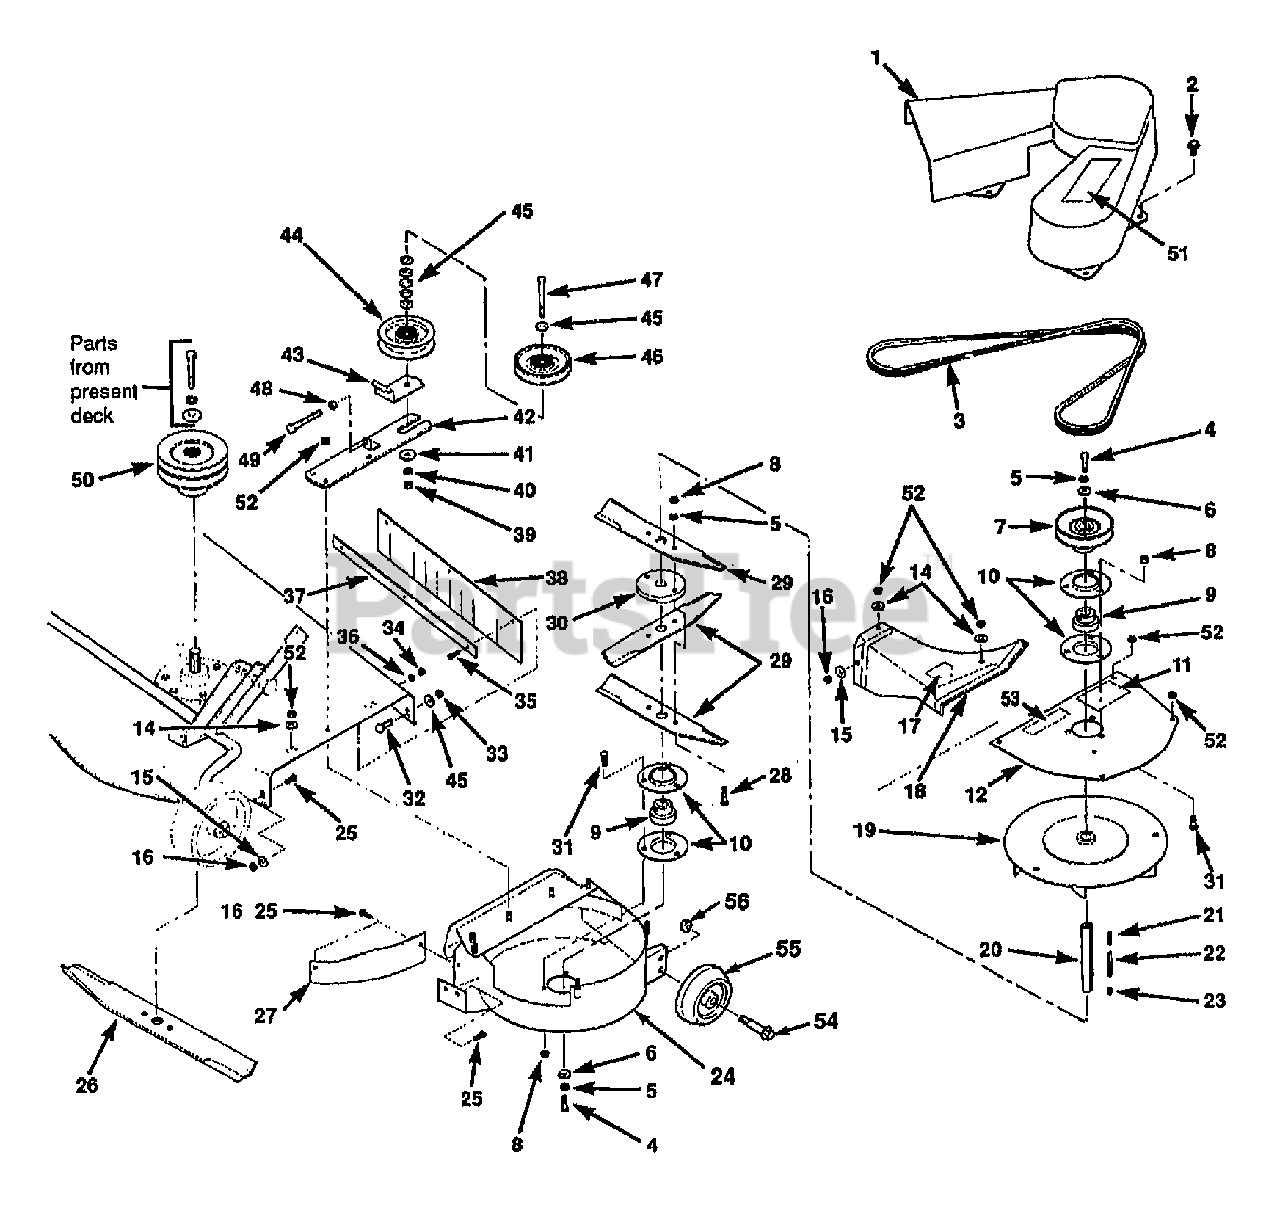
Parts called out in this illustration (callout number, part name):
1	COVER-BELT
2	SCR-THRD FRM 1/4-14X.50
3	BELT-DRIVE
4	SCR-HH 5/16-18X1.0 G5 ZP
5	WASHER-LK .312 ZP
6	WASHER-.312 X 1.378
7	SHEAVE-DRIVEN
8	NUT-TOP/LK 5/16-18 ZP
9	BEARING-BALL
11	DECAL-BELT INSTALLATION
12	COVER-HOUSING
14	WASHER-FLAT 5/16 SAE
15	WASHER-FLAT 1/4 SAE
16	NUT-HF/LK 1/4-20 ZP
17	DECAL-OPEI CAUTION
18	DEFLECTOR-DISCH W/DECAL
21	KEY-.188 SQ X 1.0
22	KEY-.188 SQ X 2.0
23	KEY .188 SQ X.343
24	ASSM-HOUSING
25	SCR-CARR 1/4-20X.75 G2 ZP
26	BLADE-MWR LH HILIFT
27	BAFFLE-REAR
28	SCR-HH 5/16-18X1.25 G5ZP
29	BLADE-11.375"
30	HUB-BLADE
31	SCR-CARR 5/16-18X.62 G2 ZP
32	BOLT-3/8-16 X 3/4
33	NUT-HFLK 3/8-16 ZP
34	NUT-HEX M10-24
35	SCR-HH 10-24X.50
36	WASHER-LK M10
37	STRIP-RETAINER
38	SHIELD-DEFLECTOR
39	NUT-HEX 3/8-16 ZP
40	WASHER-LK .375 @ DEPL
41	WASHER-FLAT 1.25X.406X.179
42	ASSM-IDLER BRACKET
43	BRKT-ADJUSTMENT
45	WASHER-FLAT 3/8 SAE
46	PULLEY-IDLER
47	SCR-HHC 3/8-16X3.25
48	NUT-HEX 5/16-18 ZP
49	SCR-HHM 5/16-18X2.75
50	PULLEY-DRIVE DUAL GROOVE
51	DECAL-IDENTIFICATION
52	NUT-HFLK 5/16-18 ZP
53	DECAL-DANGER
54	SCR-SHLDR 3/8-16
55	WHEEL-GAGE
56	NUT-LOCK 3/8-16
